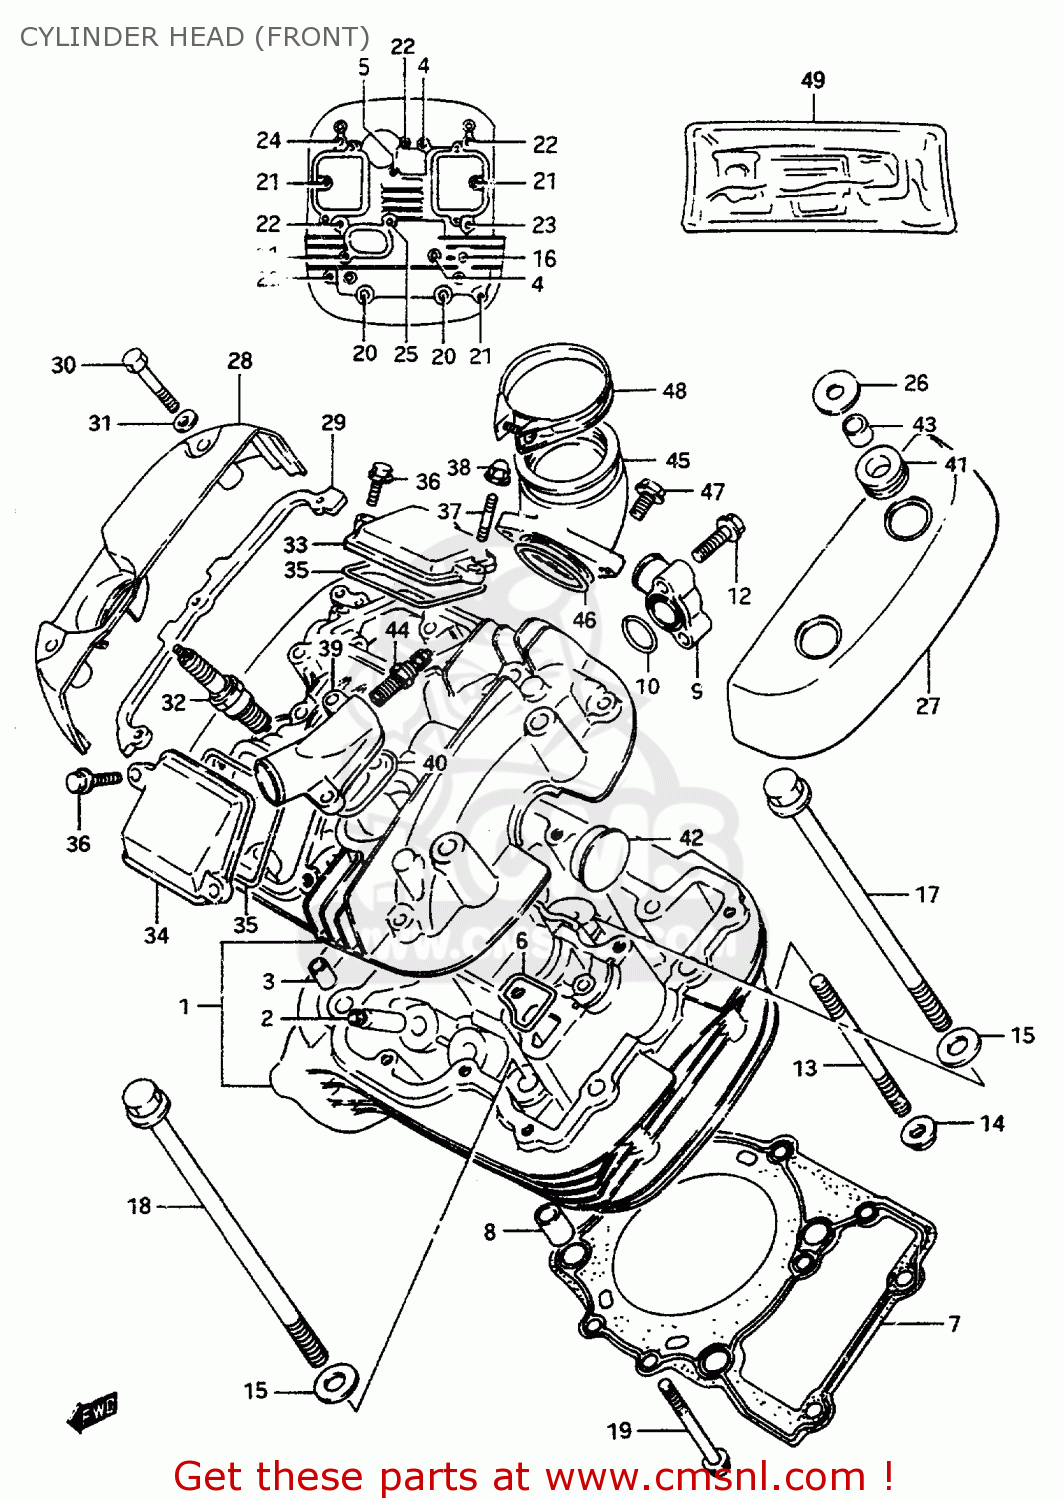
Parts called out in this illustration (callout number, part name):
1	HEAD ASSY, CYLINDER FRONT
2	GUIDE,VALVE
3	PIN(8.4X11X14)
4	BOLT(6X50)
5	BOLT(6X55)
6	GASKET,CYLINDER HEAD WATER (NAS)
7	GASKET,CYLINDER HEAD FR (NAS)
8	PIN
9	UNION,CYLINDER HEAD WATER
10	O RING(D:2.4,ID:17.8)
11	BOLT
12	BOLT
13	BOLT,STUD
14	NUT
15	WASHER (10.5X22X2.3)
16	BOLT(8X140)
17	BOLT(10X155)
18	BOLT(10X165)
19	BOLT
20	BOLT(8X245)
21	BOLT
22	BOLT
23	BOLT
24	BOLT
25	BOLT(6X55)
26	WASHER (8.2X24X1.6)
27	CAP,CYLINDER HEAD COVER FR,L
28	CAP,CYLINDER HEAD COVER FR,R
29	CUSHION,FR,R CAP
30	BOLT
31	WASHER
32	PLUG,SPARK(DPR8EA-9)
33	CAP,INSP.INT
34	CAP,INSPECTION,EXHAUST
35	GASKET,INSPECTION CAP (NAS)
36	BOLT
37	STUD 6X16
38	NUT
39	UNION,WATER OUTLET
40	GASKET,WATER OUTLET UNION (NAS)
41	CUSHION
42	PLUG(OD:30)
43	BUSH
44	GAUGE ASSY,WATER TEMP
45	PIPE,INTAKE,FRONT
46	O-RING (D:2.4 ID:39.7)
47	BOLT
48	CLAMP
49	GASKET SET
